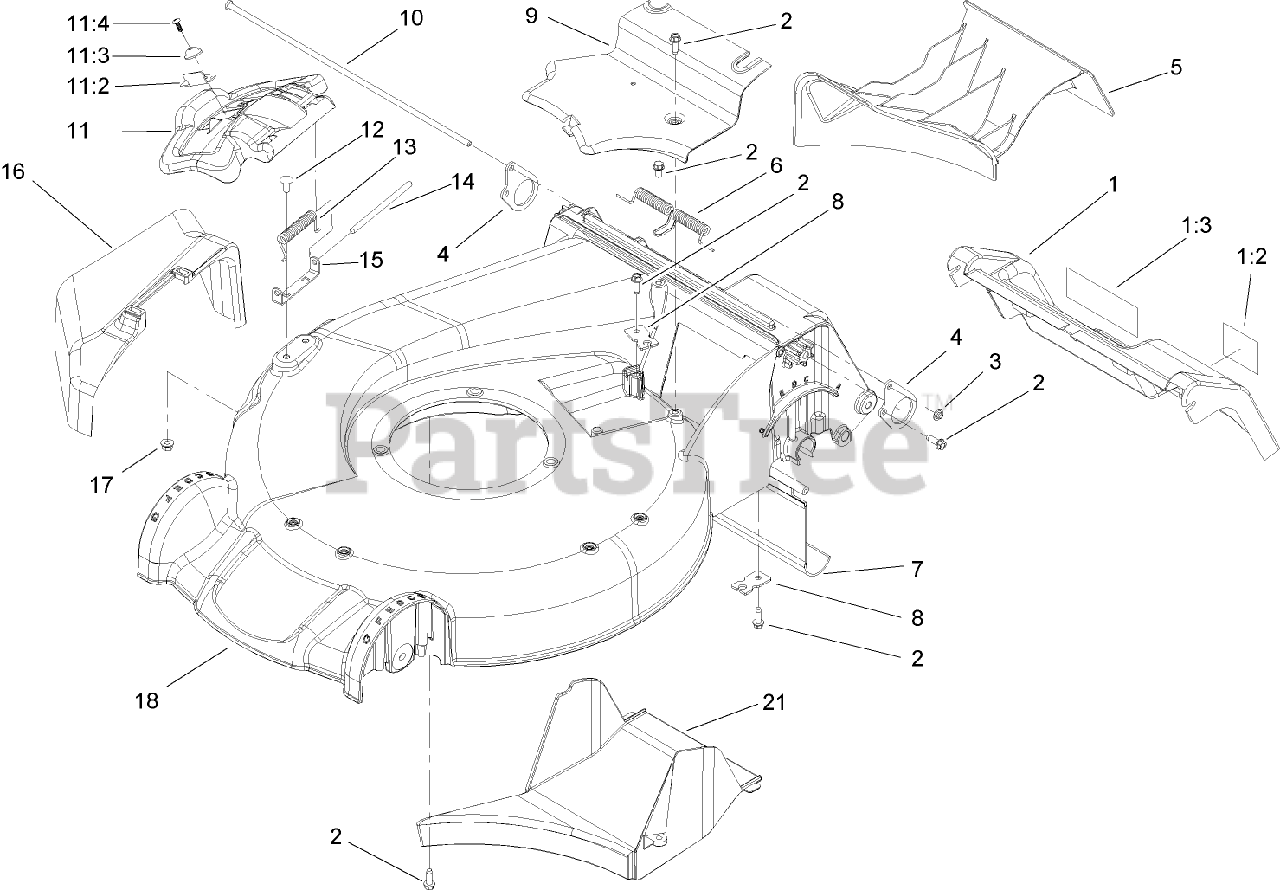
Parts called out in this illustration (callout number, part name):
1	REAR DOOR ASM
1:2	DECAL-WARNING
1:3	DECAL-WARNING
2	SCREW-HWHTF
3	NUT-SPEED
4	PLATE-SUPPORT, DOOR
5	MULCH PLUG ASM
6	SPRING-DOOR, REAR
9	COVER-BELT
10	ROD-SUPPORT, DOOR
11	DISCHARGE DOOR ASM
11:2	LATCH-DOOR
11:3	CAP-DOOR
11:4	SCREW-PLASTITE
12	SCREW-CARR
13	SPRING-TORSION
16	CHUTE-DISCHARGE, SIDE
17	NUT-HHF
18	HOUSING ASM
21	TUNNEL-DISCHARGE
